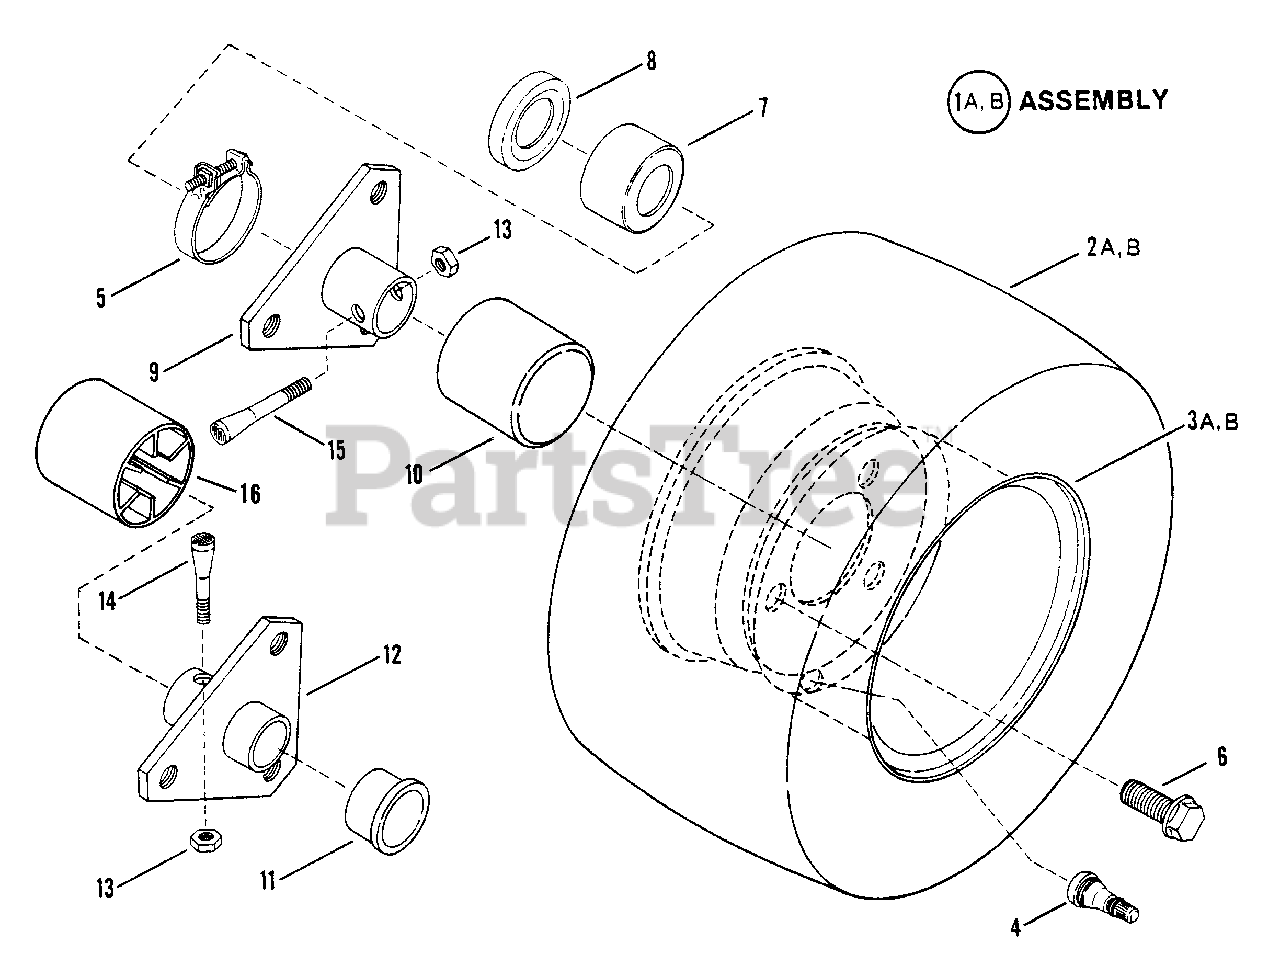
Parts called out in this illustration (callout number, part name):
1A	ASSEMBLY, Rear Tire & Rim
1B	ASSEMBLY, Rear Tire & Rim
2A	TIRE, 16 x 4.80 - 8
2B	TIRE, Wide, 16/6.50 x 8 (Stud)
3A	RIM, Std.
3B	RIM, Wide
4	VALVE, Air (Snap-in)
5	CLAMP
6	BOLT, 1/2-20 x 3/4" Lug
7	CAP, Seal (Right Hand)
8	SEAL, Oil
9	HUB, Rear Wheel (Right Hand) 1.126" ID
10	CAP, Hub
11	CAP, Seal L.H. 3/4"
12	HUB, Rear Wheel (Left Hand) .75" ID
13	NUT, 5/16-24 Hex Center Lock
14	BOLT, 5/16-24 x 1-5/8" Tapered (Left Hand)
15	BOLT, 5/16-24 x 2" Tapered (Right Hand)
16	CAP, Hub
